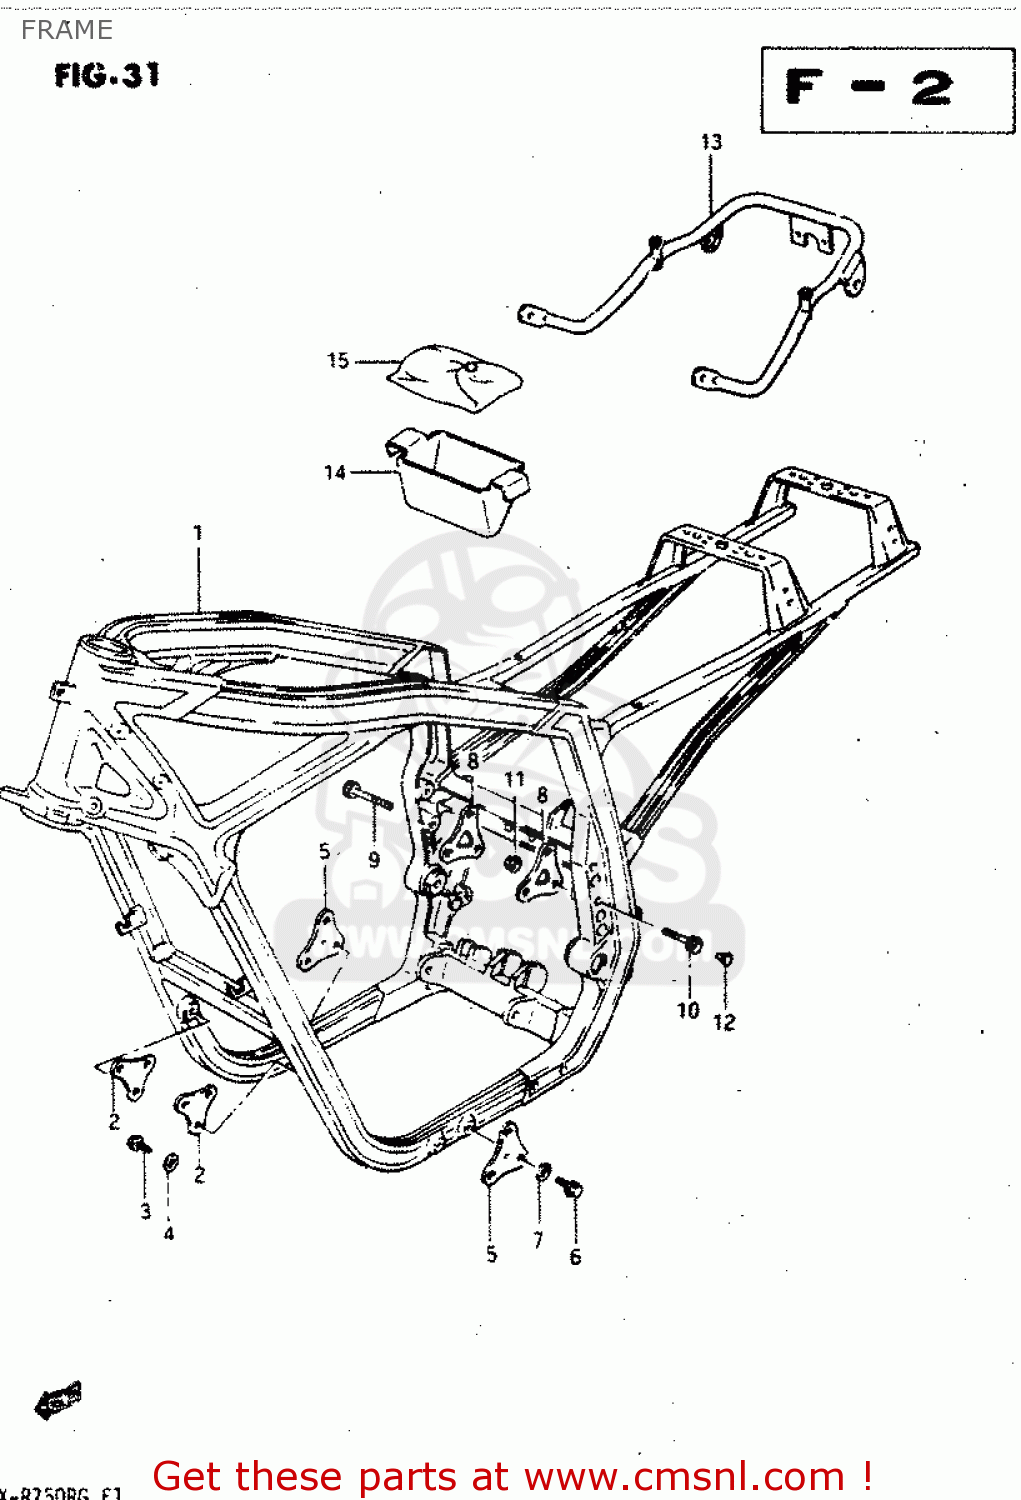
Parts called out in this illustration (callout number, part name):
1	FRAME
2	PLATE,ENGINE MOUNTING NO
3	BOLT
4	WASHER (8.2X20X1.6)
5	PLATE,ENGINE MOUNTING NO.1
6	BOLT
7	WASHER (8.2X20X1.6)
8	PLATE,ENGINE MOUNTING NO
9	BOLT, RH
10	BOLT
11	NUT
12	CAP,ENGINE MOUNTING
13	GRIP COMP,REAR
14	HOLDER,TOOL
15	TOOL ASSY
